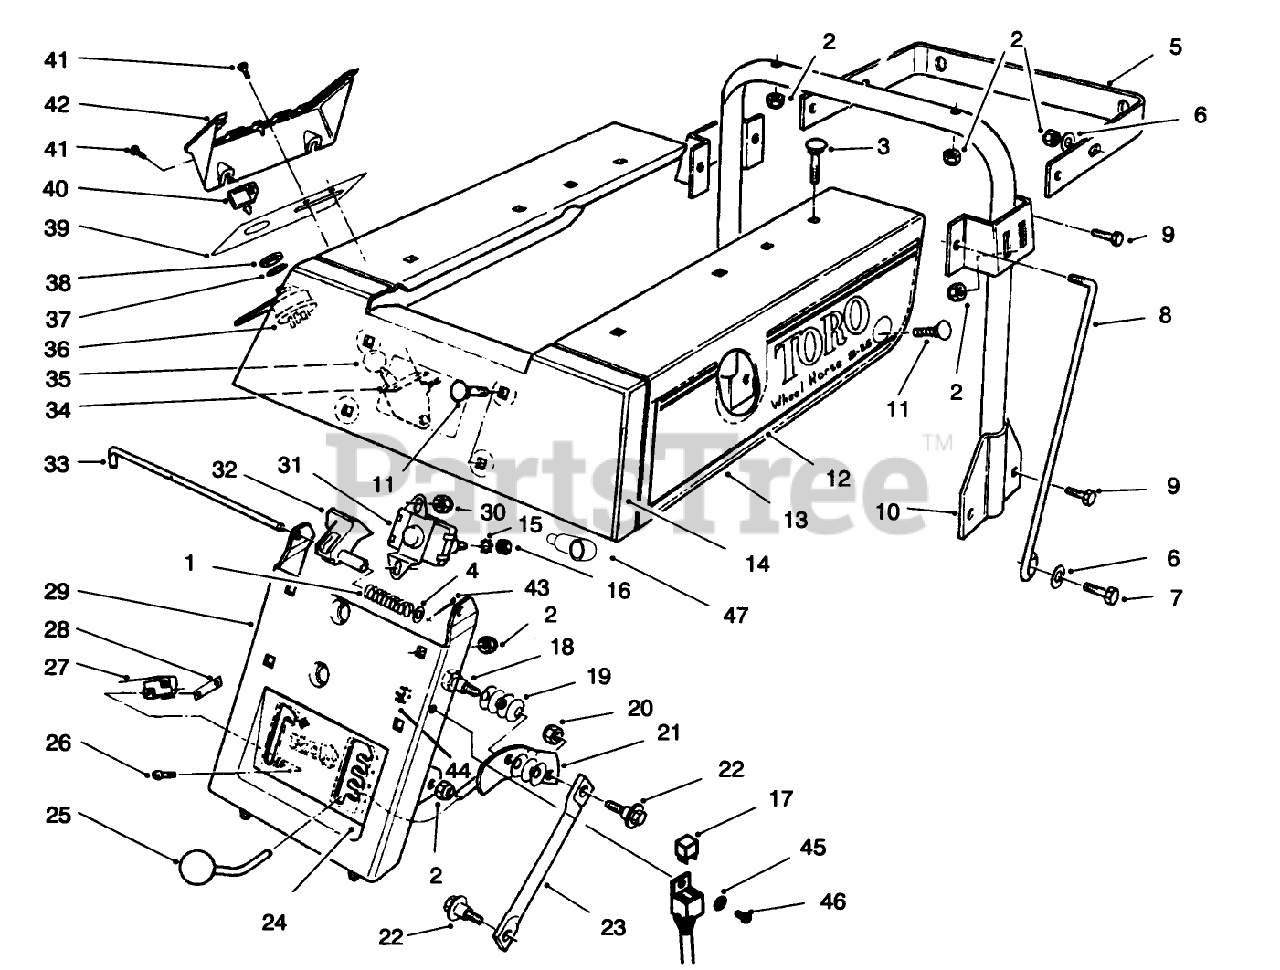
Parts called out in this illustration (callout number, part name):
1	SPRING-COMPRESSION
2	NUT-LOCK, NI
3	SCREW-CARR
4	WASHER-FLAT
5	Bar-Stand
6	WASHER-PLAIN
7	SCREW-HH
8	BRACE-SEAT SUPPORT
9	SCREW-HH
10	SEAT SUPT ASM
12	DECAL - LH SIDE PLATE
13	SEAT BODY WA
14	DECAL - W.H. INSIGNA
15	WASHER-LOCK
16	NUT-JAM
17	RELAY
18	BOLT-SHOULDER
19	WASHER-BELLEVILLE
20	NUT-LOCK, NI
21	HOC HDLE WA
22	BOLT-SHOULDER
23	LINK-HOC
24	DECAL - HOC/DECK ENGAGE
25	KNOB-CONTROL
26	SCREW-SPH
27	SWITCH-MICRO
28	NUT-SPEED
29	SEAT SUPPORT ASM
30	NUT-LOCK, NI
32	PROP-SEAT
33	ROD-SEAT BASE
34	CONTROL-THROTTLE
37	WASHER-LOCK
38	NUT-HH
40	KEY-IGNITION
41	SCREW-THD FORM, HWH
43	PIN-COTTER
44	NUT-LOCK, NI
45	WASHER-FLAT
47	BOOT-INSULATOR, TERMINAL
